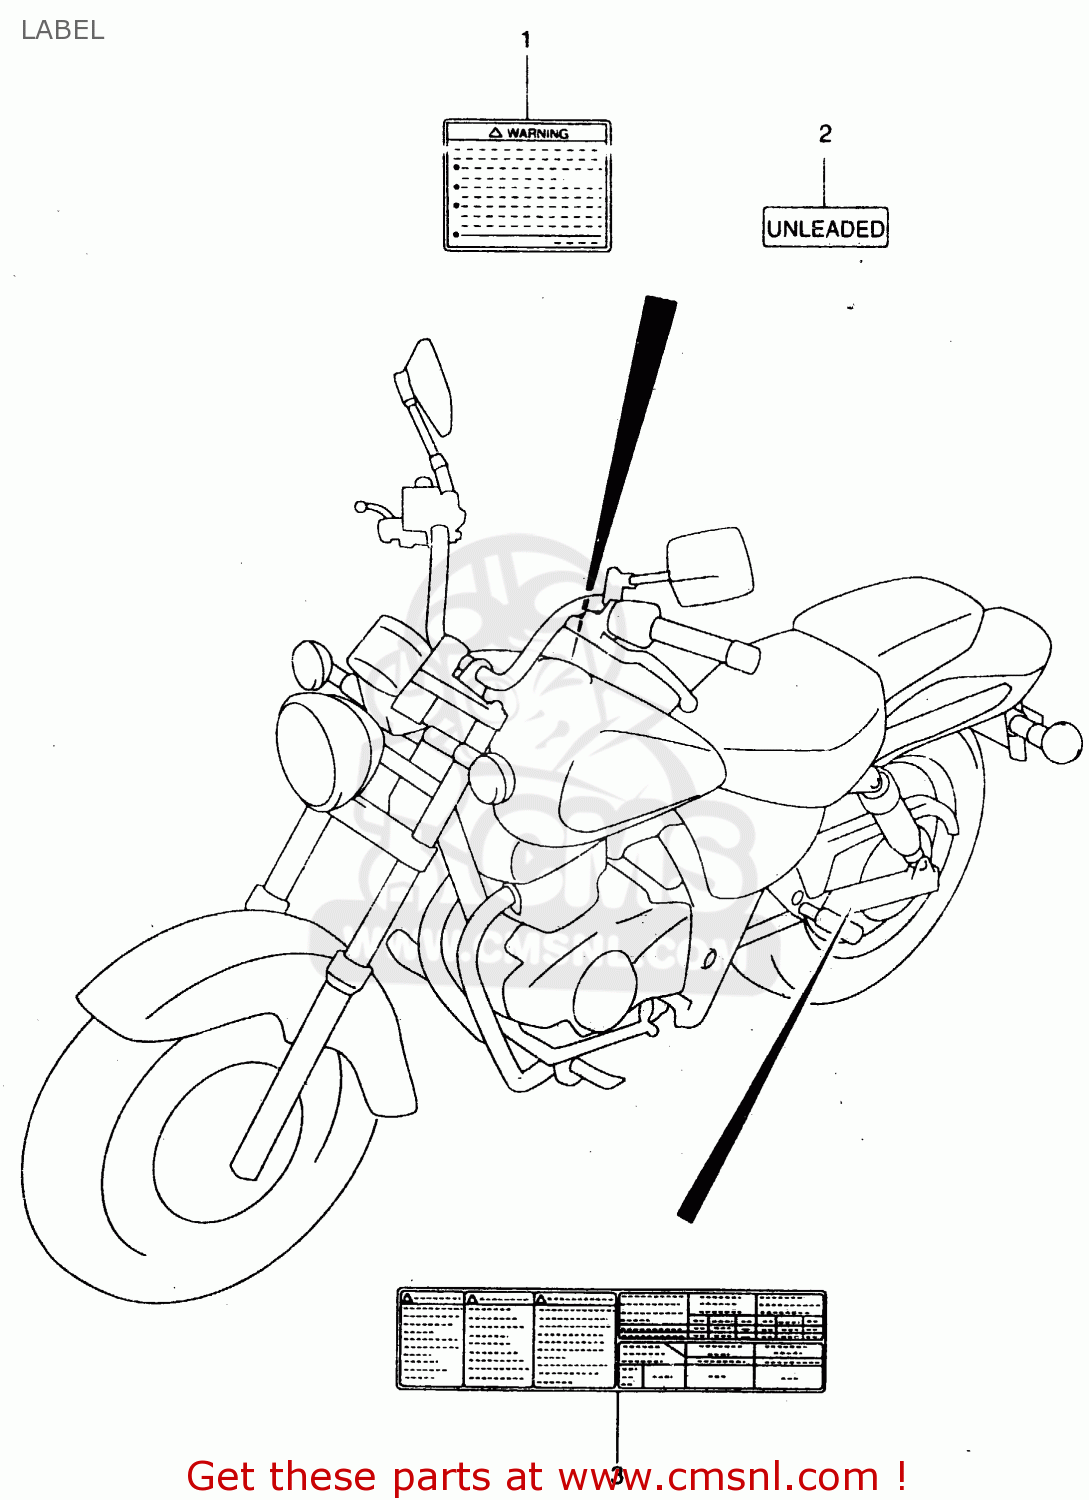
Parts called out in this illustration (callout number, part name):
1	LABEL,WARNING
2	LABEL,CAUTION
3	LABEL, TIRE INFORMATION
